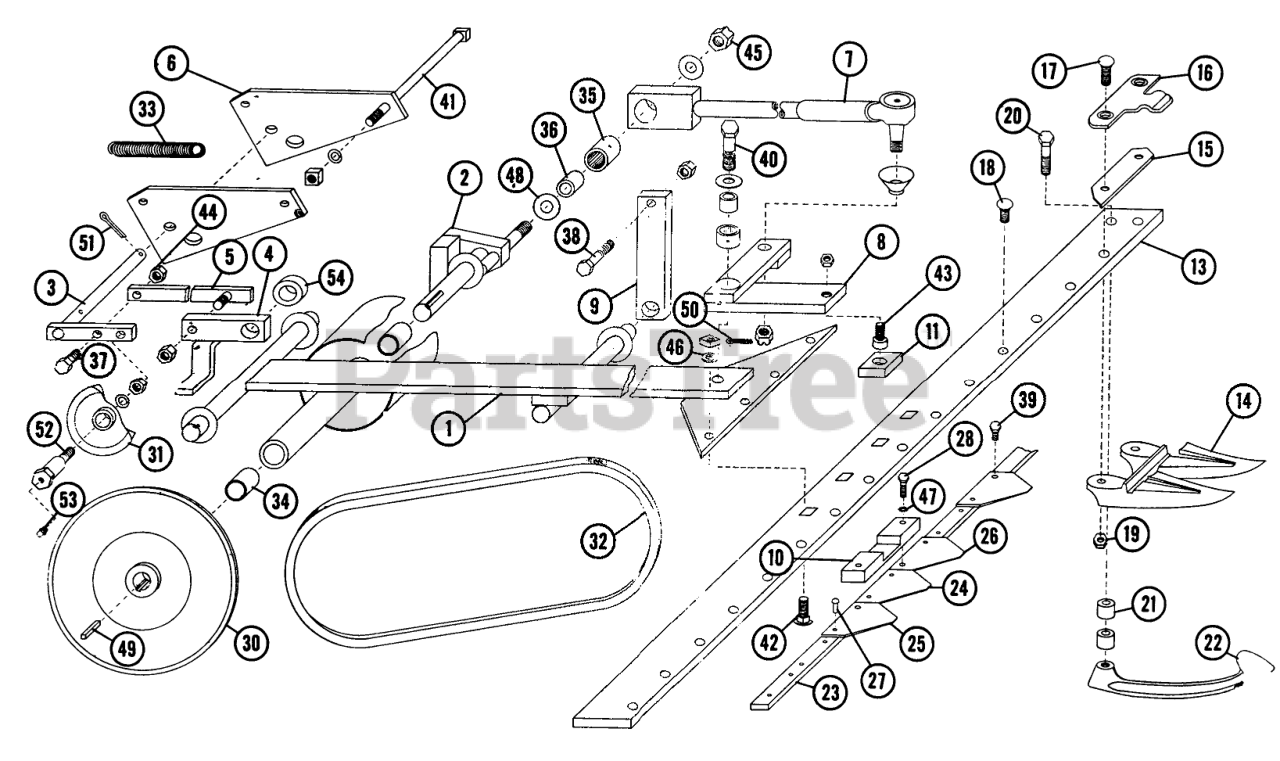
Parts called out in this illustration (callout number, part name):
1	Spacer
2	Crankshaft Assembly
3	Idler Lever Assembly
4	Pedal, Clutch
5	Link, Clutch
6	Hanger Plate
7	Pitman Assembly
8	Rocker Arm Assembly
9	Lift Link
10	Saddle Block
11	Drive Block
12	Cutting Unit Complete
13	Guard Bar
14	Twin Guard
15	Wear Plates
16	Clip, Hold Down
17	Plow Bolt, 3/8-16 x 1 1/4
18	Plow Bolt w/nut
19	Hex Nut
20	Hex Hd. Cap Screw 3/8-16 x 1 3/4
21	Spacer
22	Skid
23	Knife Bar
24	Section
25	Knife Section, R.H.
26	Knife Section, L.H.
27	Rivet
28	Inner Felt Seal
29	Knife Assembly, Includes No. 23, 24, 27
30	V-Pulley
31	Idler Pulley
32	V BELT
33	Spring
34	BUSHING-BRONZE
35	NEEDLE BEARING
36	Inner Race
37	Hex Head Cap
38	Hex Head Cap Screw
39	Felt Seal
40	O-Ring
41	Machine Bolt 3/8 x 7
42	Spring Clip
43	Soc. Hd. Cap Screw 3/8-16 x 3/4
44	31300 '65-67&UP 20
45	Bearing Cup
46	Lockwasher
47	Lockwasher, 1/4
48	S.A.E. Washer
49	KEY-STRAIGHT
50	Cotter Key
51	Cotter Pin
52	Shoulder Bolt
53	Zerk
54	Collar
